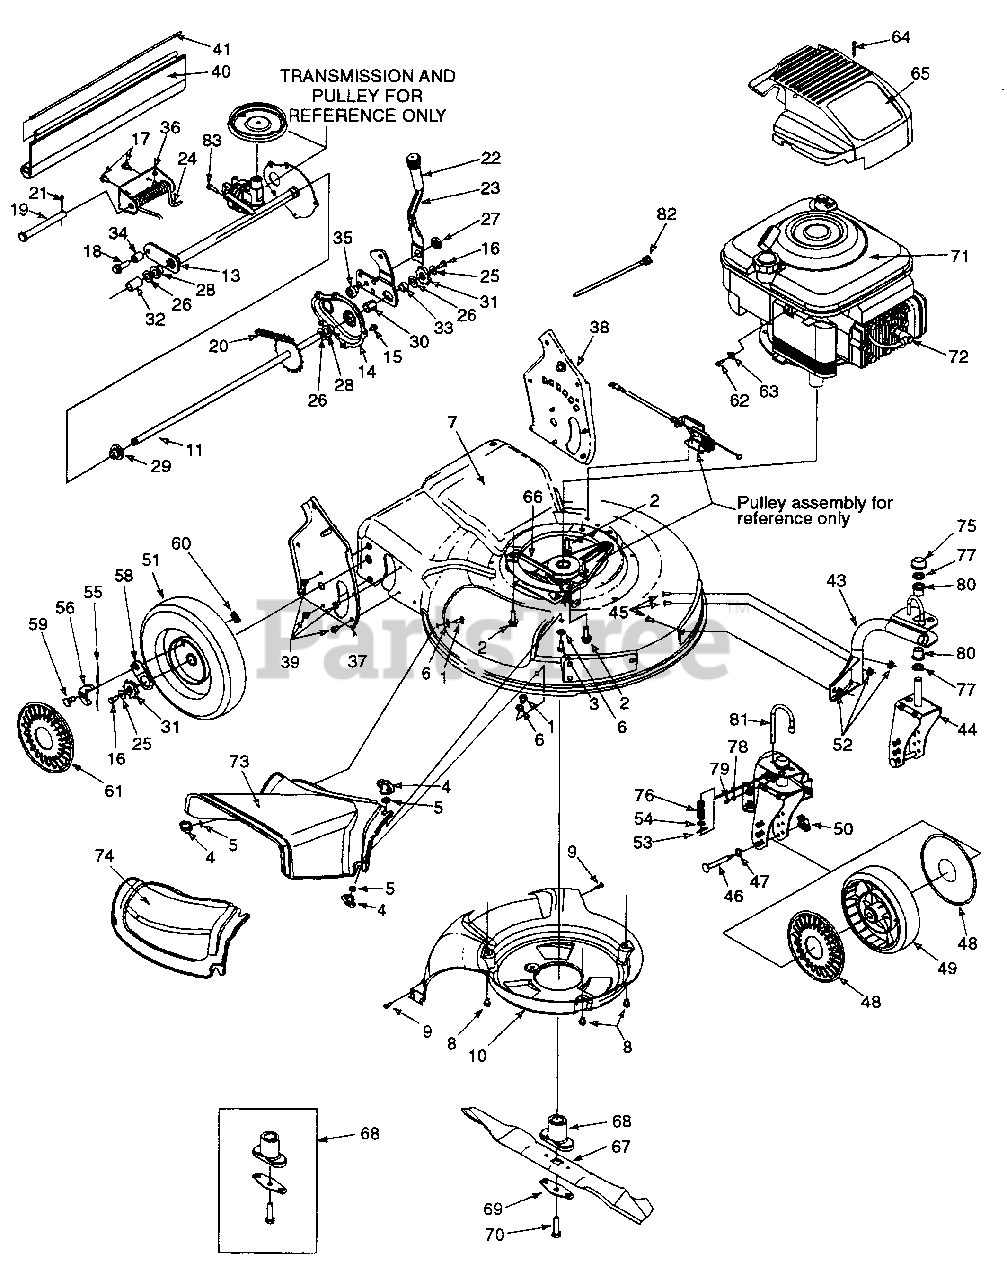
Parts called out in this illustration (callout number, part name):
1	Carriage Bolt 1/4-20 x .62" Lg.
2	Scr. TT:3/8-18:1.00
3	Scr. 1/4-20 x .750
4	Wing Nut 1/4-20
5	Nut, Push .25 I.D. x .50 O.D.
6	Wash. Fl. .334 I.D.x .62 x.03
8	Scr. Tt. 1/4-20 x .375
9	Scr. Hl. 1/2-14 x .750
10	Baffle
11	Rear Axle Ass'y
16	Cap Screw HH 1/4-20 x .620
17	Scr. AB 1/4-14 x .825
18	Scr. 3/8 116 x .25
19	Clevis Pin .50 Dia. x 4.82 Lg.
20	Chain-Endls. #48 .500P x 24L
21	Cotter Pin .125 O.D. x .75
23	Spring Lever
24	Torsion Spring
25	Bell Wash. .285 x .75 x .082
26	Fl. Wash. .508 I.D. 1.000 x.020
27	Nut Shld. .825 Dia. x .165 Lg.
28	Hx. Flg. Brg. .506 I.D. x .590 L.
29	Hx. Flg. Brg. .506 I.D. x.715 L.
30	Hx. Slv. Brg. .504 I.D. x .830 L.
31	Wheel Rachet
32	Spa. .550 I.D. x .750 O.D.
33	Spa. .51 .D. x .70 O.D. x 38 L.
34	Spa. .835 x .624 x .700
35	Shld. Spa. .835 I.D. X .715 Lg.
40	Trail Shield
41	Trail Shield Wire
45	Carr. Bolt 5/16-18 x.62
46	Caster Axle .374 Dia x 2.50"
47	Wave Washer
48	Hub Cap w/Hole
49	Wheel 7 x 2
50	Wing Nut 1/4-20
51	Wheel 9 x 2
52	Lock Nut 5/15-18
53	Cotter Pin .072 x .12 Lg.
54	Fl. Wash. .330 x .830 x .060
55	Spring, Ratchet, Plastic
56	Pawl - R.H.
58	Ratchet Pawl Plate
59	Scr. Shld. .340 x .285
60	Top Lock Tab Weld Nut 1/4-20
61	Hubcap
62	Screw .620 Hx. Slt. Wsh.
63	Casing Clamp, Throttle
64	Shroud Screw
65	Engine Shroud
66	Belt
67	21" Mulching Blade
68	Blade Adapter Kit
69	Blade Bell Suport
70	Hex Bolt 3/8-24 x 2.5"Lg.
71	Engine
72	Spark Plug Insulator
73	Side Discharge Chute
74	Mulch Cover
76	Compression Spring
77	Fl. Wash. .5/8 I.D. x 1" O.D.
78	Fl. Wash. .203 x .403 x .404
79	Fitting - Grease
80	Flange Bearing
81	Locking Pin
82	Cable Tie
83	Hex Scr. 5/16-18
